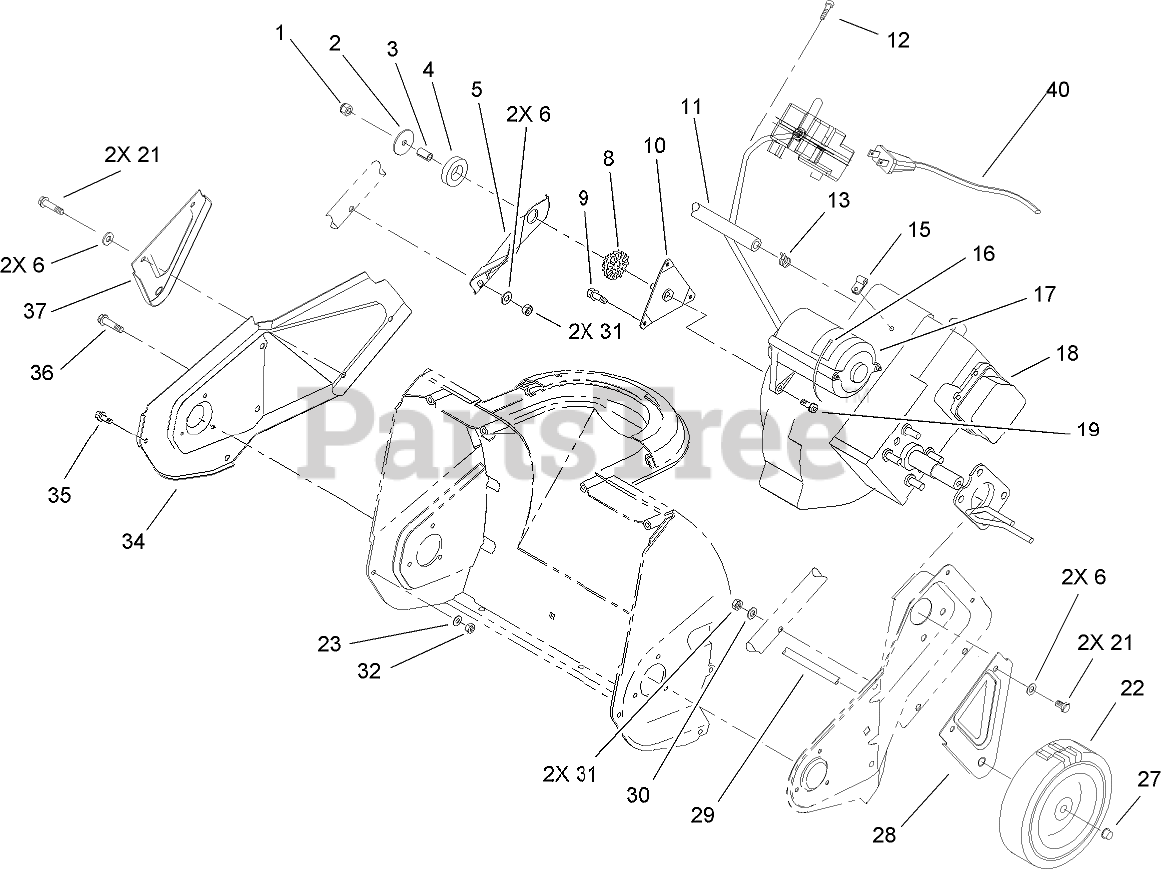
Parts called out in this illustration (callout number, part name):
1	NUT-LOCK, NI
2	WASHER-FLAT
3	SPACER-TUBULAR
4	RING-ISOLATOR
5	BRACKET-SUPPORT, ENGINE
6	WASHER-FLAT
8	BUSHING-ISOLATOR
9	SCREW
10	BRACKET AND STUD ASM
11	HOSE-FUEL
12	SCREW-PLASTITE
13	CLAMP-HOSE
15	CLAMP
16	TIE-CABLE
17	120 VOLT STARTER ASM
19	SCREW-HH, TORX
21	SCREW-HH
22	WHEEL
23	WASHER-FLAT
27	RETAINER-PUSH ON
28	BRACKET-WHEEL, LH
30	WASHER
31	NUT-LOCK, NI
32	NUT-LOCK, NI
34	PLATE-SIDE, RH
36	SCREW-PLASTIC
37	BRACKET-WHEEL, RH
40	CORD-ELECTRIC
